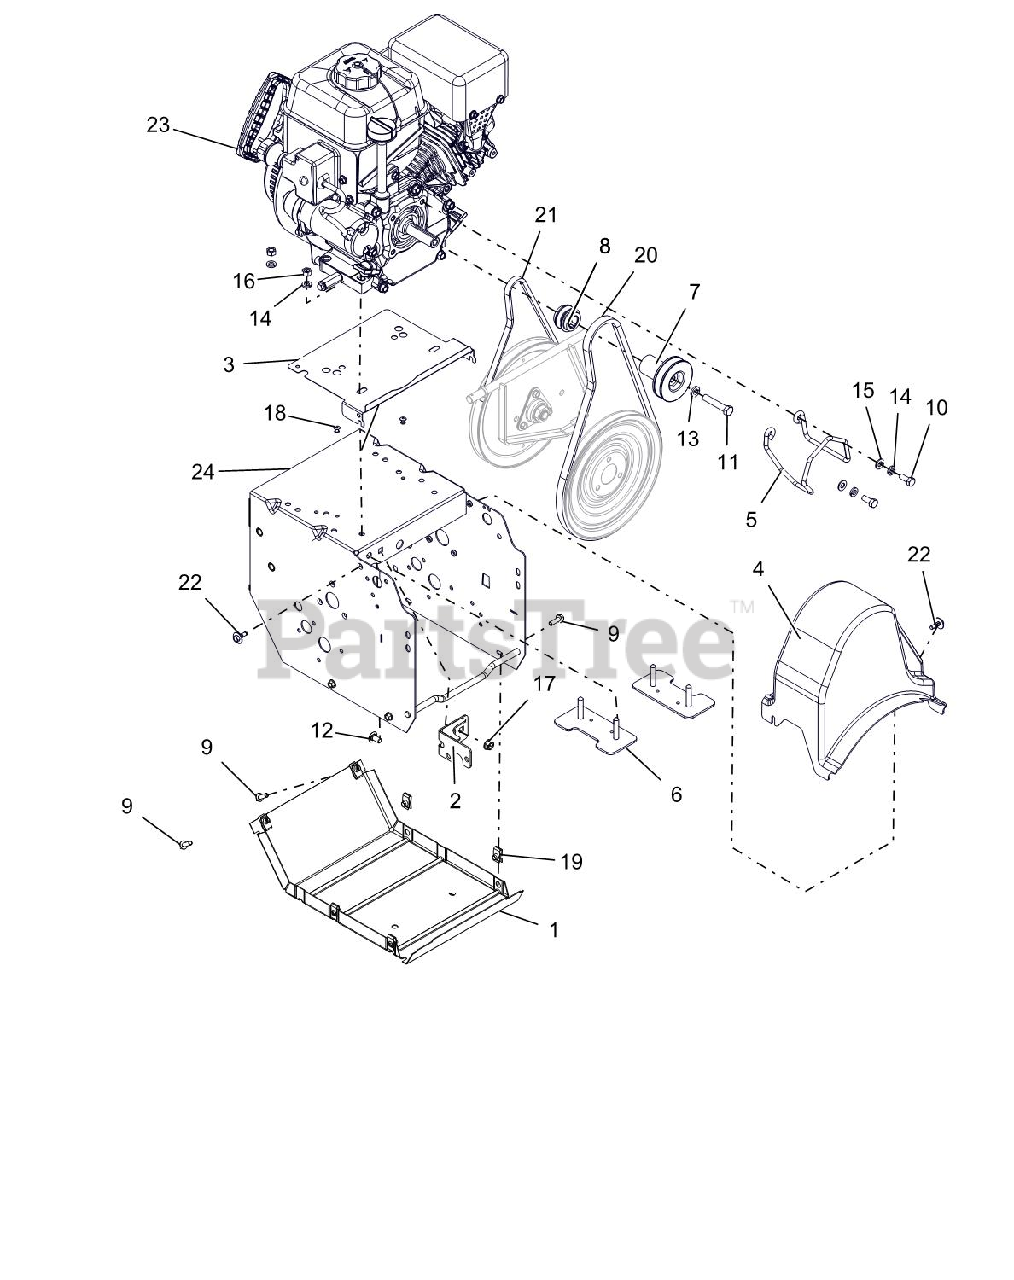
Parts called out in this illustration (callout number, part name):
1	COVER, BOTTOM
2	WELDMENT, FRAME BRACKET
3	BAFFLE, COMPACT
4	COVER, COMPACT BELT
5	FINGER, BELT
6	STRAP, ENGINE BOLT-WELDMENT
7	SHEAVE, AUGER 3/4 - PM
8	TRACTION SHEAVE HALF
9	BLT-HEX .25-20X.75 HWH YZ GR5
10	BLT-HEX .31-24X.75 YWZC GR5
11	BLT-HEX .38-24X2.0 YWZC
12	@BLT-RHDSSQNK .31-18X.62 G5YZ
13	WSHR-LK .375X.115 HVY YWZC
14	WSHR-LK .312X.097 HVY YWZC
15	@WSHR-FL-STL.344X.688X.065YWZC
16	@NUT-HEX .31-18 YWZC
17	@NUT-LK-TOP-FLG .31-18 YWZC
18	RVT-POP .187 YZ
19	NUT-RTNR .25-20X.56
20	V-BELT, HA-RAW EDGE
21	V-BELT, 3L-WRAPPED
22	SCR-TAP .25-20X.5 CAPTIVE
23	ENGINE, SNO-TEK 208 120V
24	FRAME W/ENGINE BOLT STRAPS
